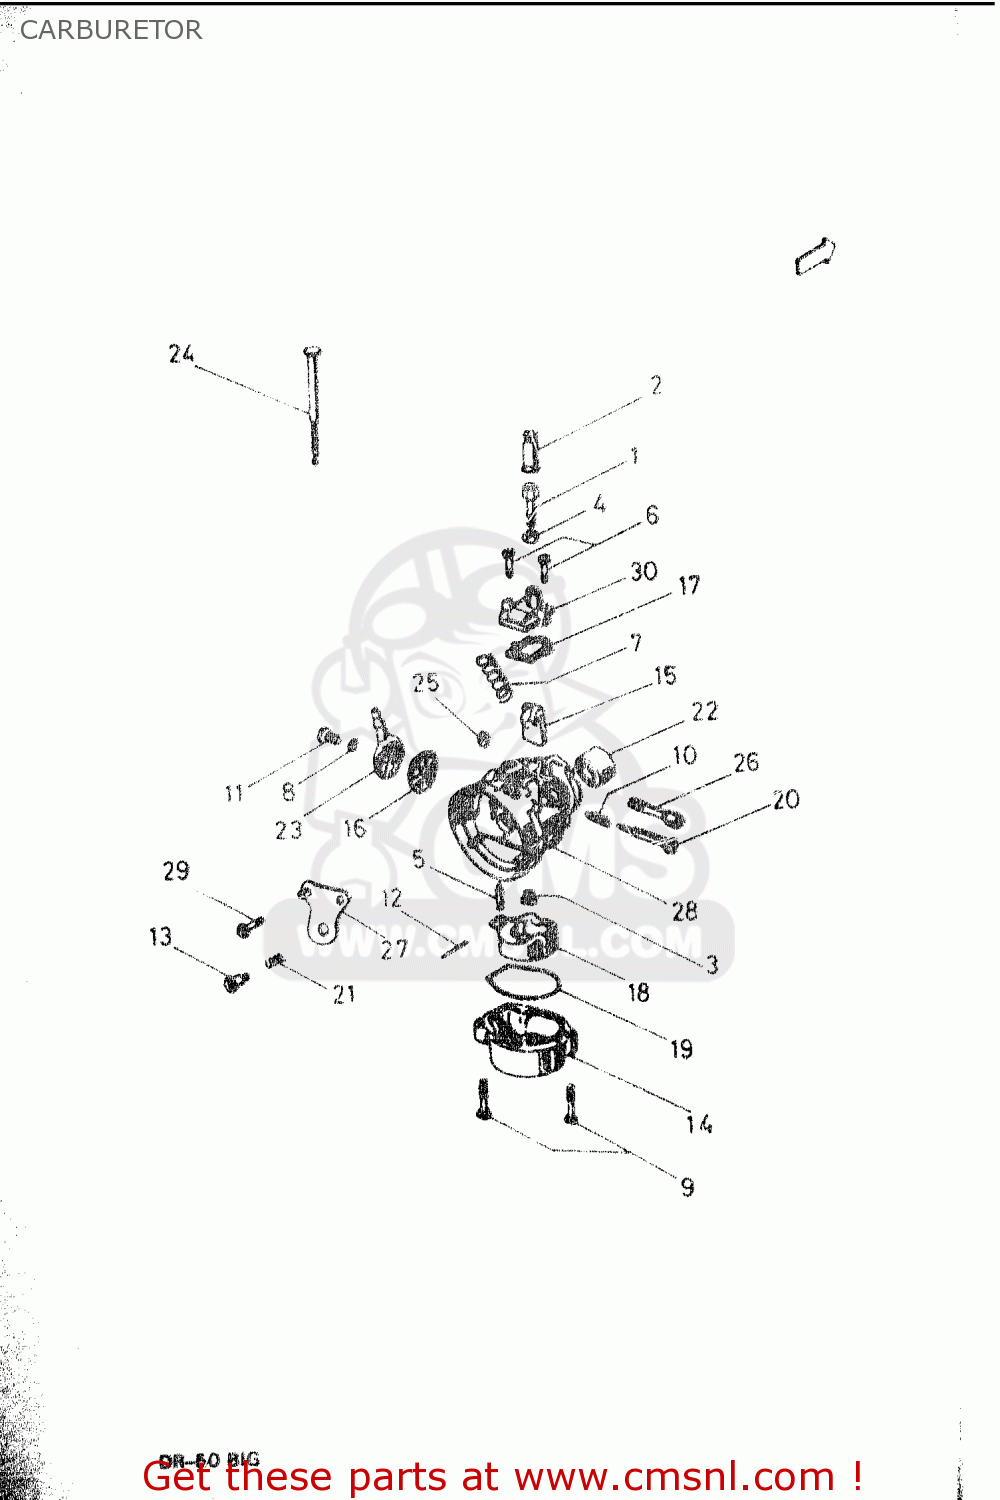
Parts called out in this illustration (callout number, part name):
1	SCREW
2	CAP
3	JET, MAIN (57)
4	SCREW
5	NEEDLE, JET
6	SCREW
7	SPRING
8	GASKET
9	SCREW
10	SPRING
11	SCREW
12	PIN, FLOAT
13	SCREW
14	CARBURETOR BOWL
15	GATE
16	FILTER
17	GASKET
18	FLOAT
19	GASKET
20	SCREW ADJUSTER
21	SPRING, DIAPHRAGM
22	BUSH
23	CASK
24	DRIVING AXLE
25	NUT
26	SCREW
27	DIAPHRAGM ASSY
28	CARBURETOR BODY
29	SCREW
30	COVER
